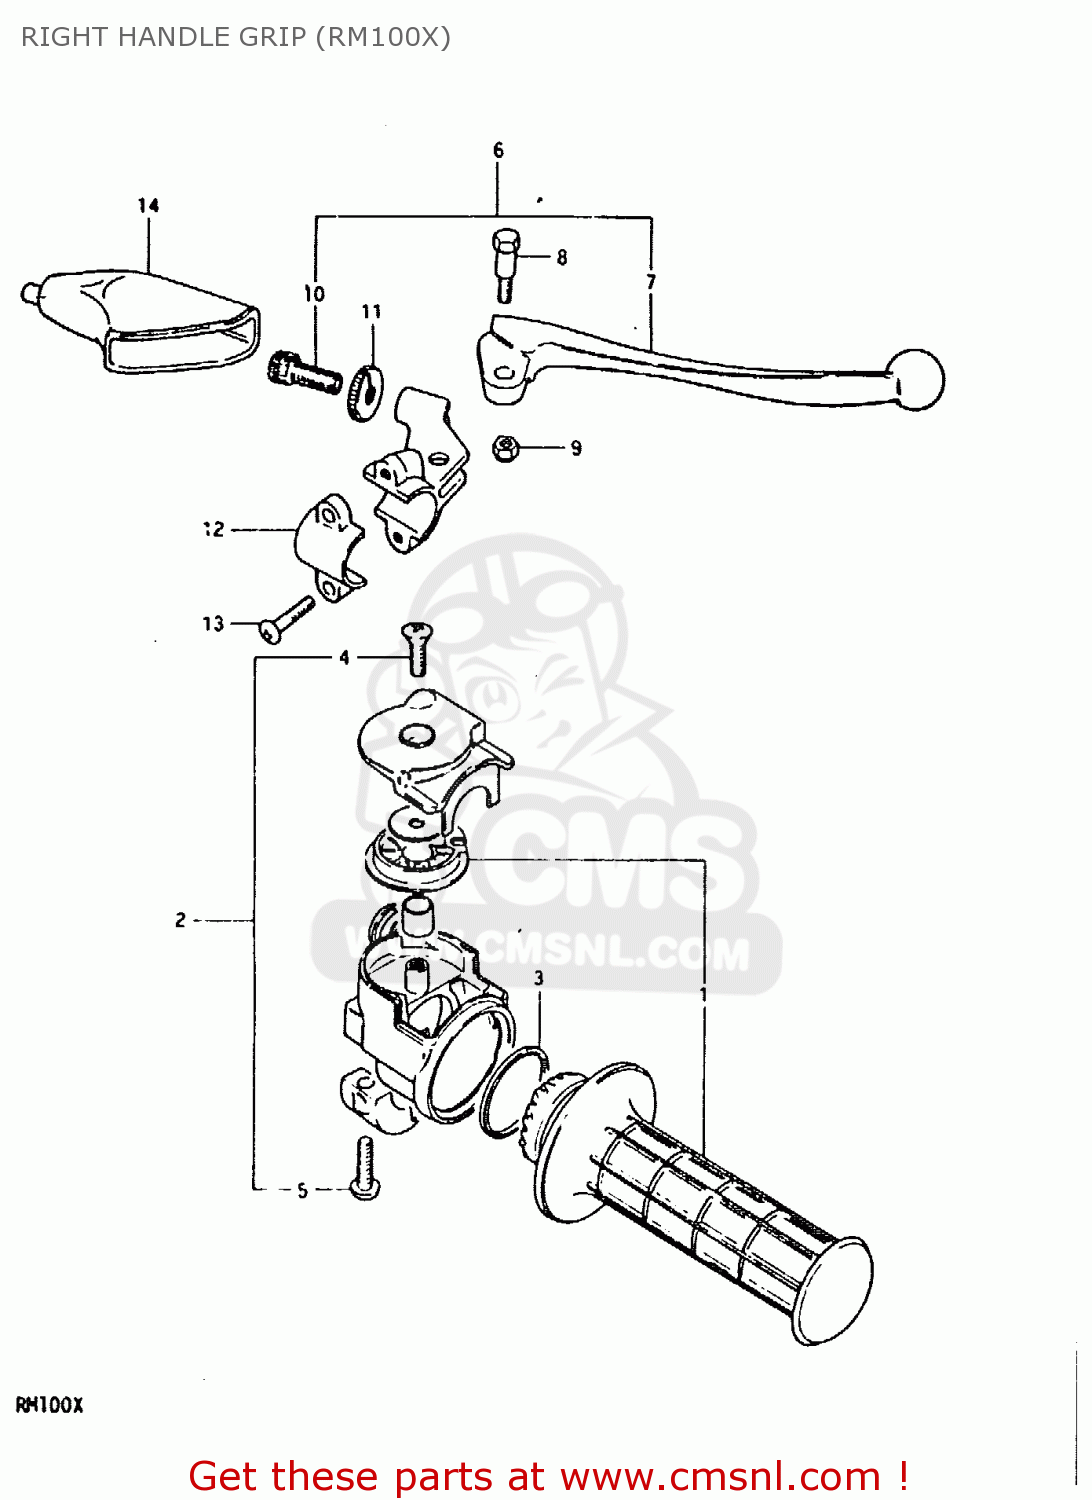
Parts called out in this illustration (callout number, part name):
1	GRIP SET,THROTTLE
2	CASE ASSY,THROTTLE
3	V-RING,THROTTLE GRIP
4	SCREW
5	SCREW 5X20
6	LEVER ASSEMBLY,BRAKE
7	LEVER,BRAKE
8	BOLT,LEVER
9	NUT 6MM
10	ADJUSTER,CABLE
11	NUT,CABLE ADJUSTER
12	BRACKET,LEVER
13	SCREW
14	COVER,CLUTCH LEVER
